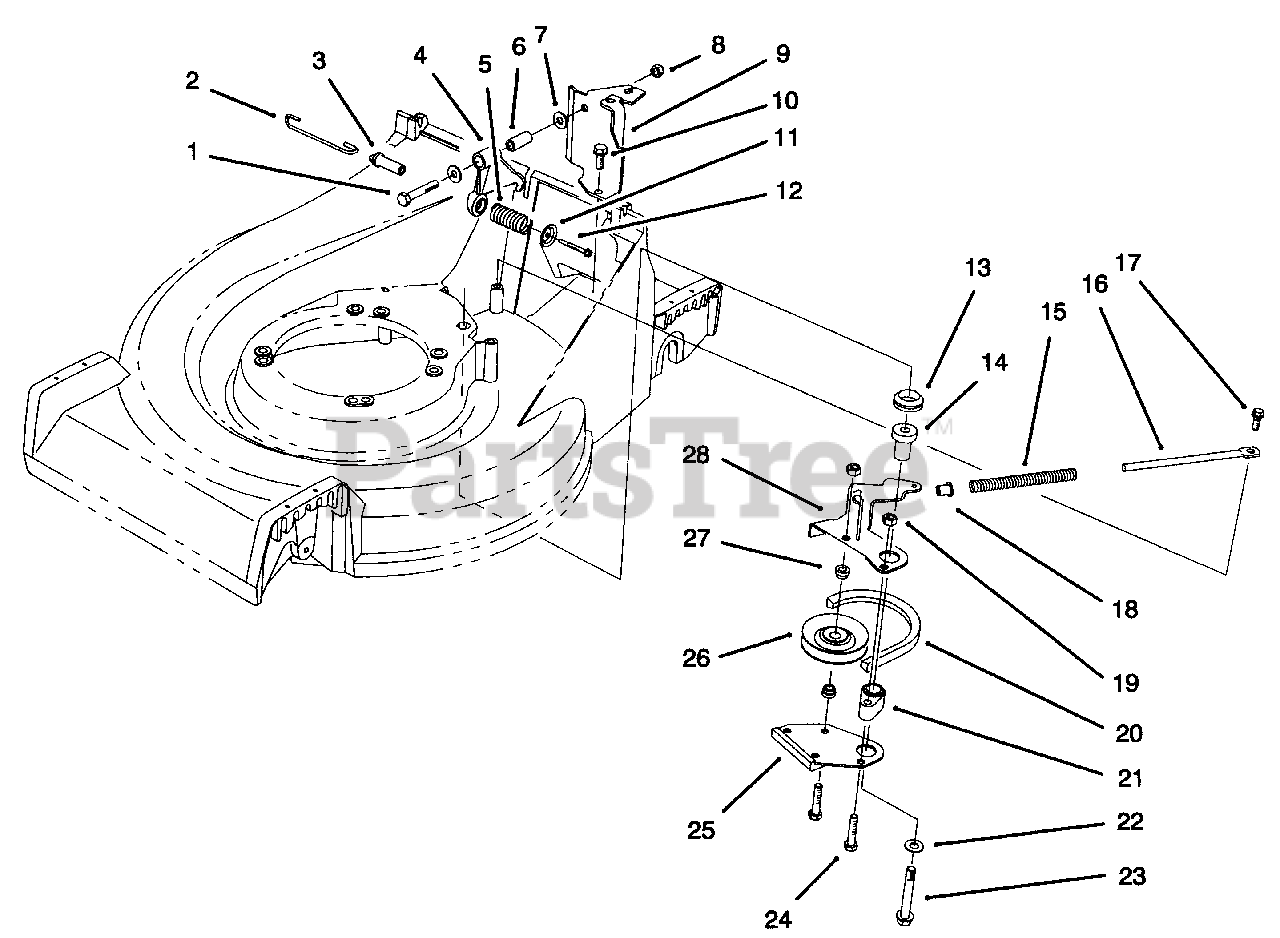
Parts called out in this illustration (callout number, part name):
1	Screw-Hex Hd. Cap
2	Link-Control
3	Pin-Spring
5	Spring-Compression
6	Bushing-Bellcrank
7	Washer-Flat
8	Nut-Flange
9	Bracket-Cable Support
10	Screw-Tapping
11	Retainer-Spring
12	Screw-Hex Washer Hd.
13	Seal-Ring "V"
15	Spring-Compression
16	Rod-Spring Brake
17	Bolt-Shoulder
18	Bushing-Flange
19	Nut-Lock
21	Hub-Plate BBC Brake
22	Washer-Flat
23	Screw-Thread Forming
24	Screw-Hex Hd. Cap
25	Shoe-Brake
26	Pulley-Idler
27	Hub-Pulley Idler
28	Lever-Brake
